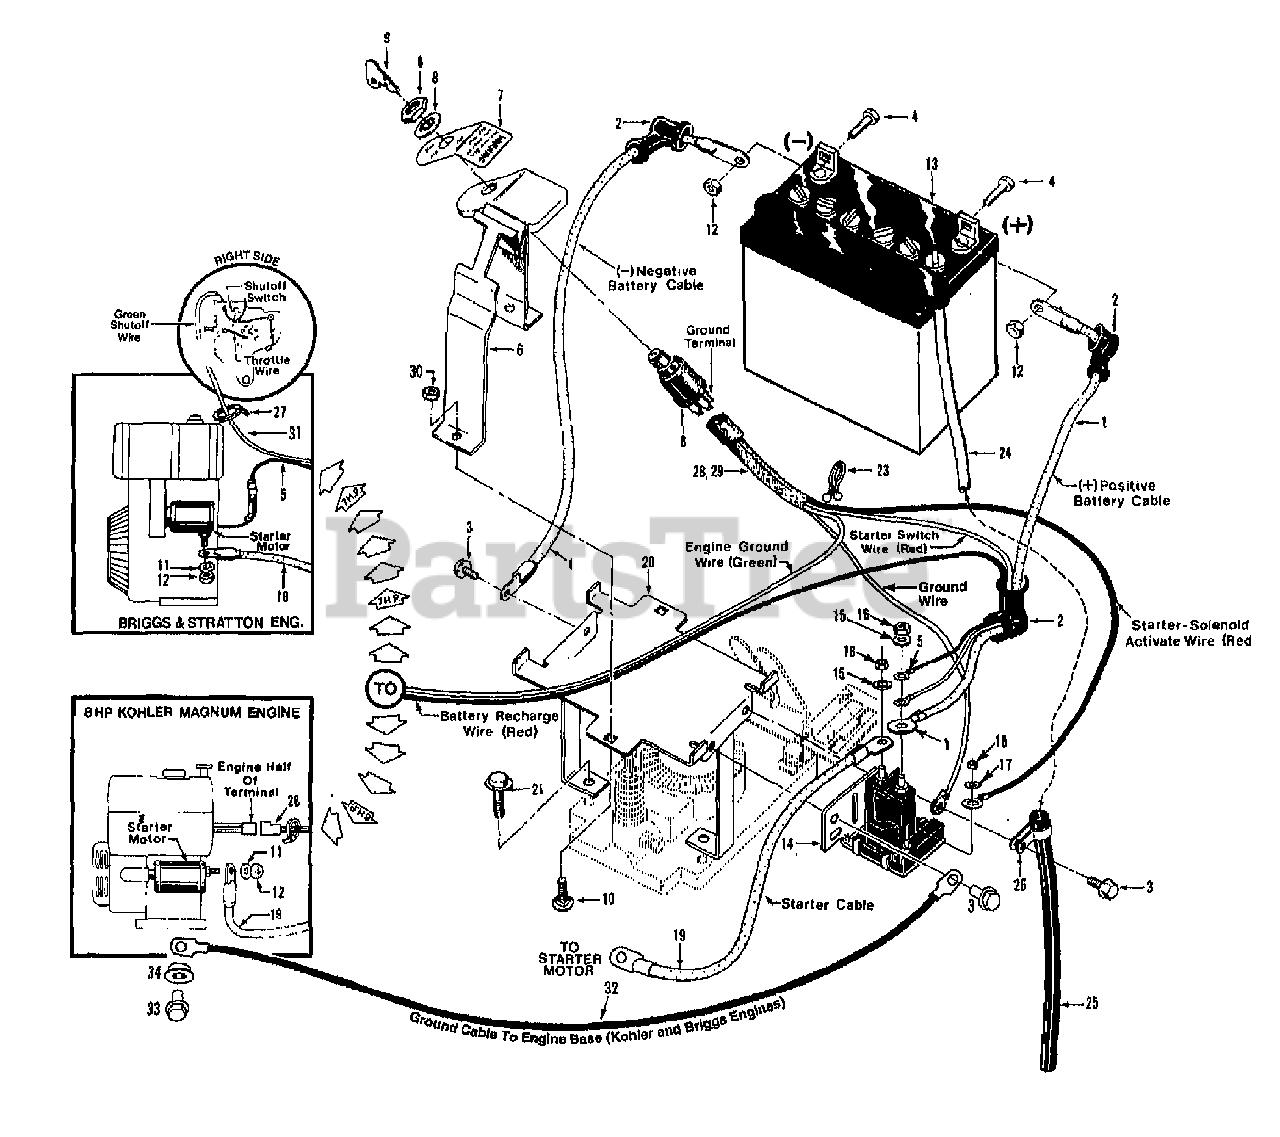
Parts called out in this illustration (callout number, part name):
1	CABLE-BATTERY 10"
2	BOOT-BATTERY CABLE
3	SCR-HWH 1/4-20 X .5 STH
4	SCR-HH 1/4-20X.625
5	WIRE-RECHARGE 5&7 BRIGGS
6	KEYSWITCH W/DECAL HORSE
7	DECAL-IGNITION TILLERS
8	ASSM-KEYSWITCH ELEC TLR
9	KEYS-IGN T/BLAZER 1 PAIR
10	SCR-CARR 1/4-20X1.25
11	WASHER-LK .25 ZP
12	NUT-HEX 1/4-20 ZP
13	BATTERY-12 VOLT HORSE
14	SOLENOID
15	WASHER-LK .312 ZP
16	NUT-HEX 5/16-24
17	WASHER-EXTERNAL TOOTH 1
18	NUT-HH M10-32X.125
19	CABLE-BATTERY 12"
20	BRKT-BATTERY OPC PNT
21	SCR-HFLK 3/8-16X1.50
22	THIS REF. NO. NOT USED
23	TIE-TWIST LOCK
24	TUBE-VENT BATTERY/HSE
25	TUBING-RUBBER
26	CLAMP
27	TIE-RED
28	KIT-WIRE HARNESS ASSM
29	ASSM-WIRE HARNESS
30	NUT-HF/LK 1/4-20 ZP
31	ASSM-WIRE SWITCH/GROUND
31	CABLE-BATTERY 15"
32	CABLE-BATTERY 15"
33	SCR-HFLK 5/16-18X1.00 ZP
34	NUT-HFLK 5/16-18 ZP
